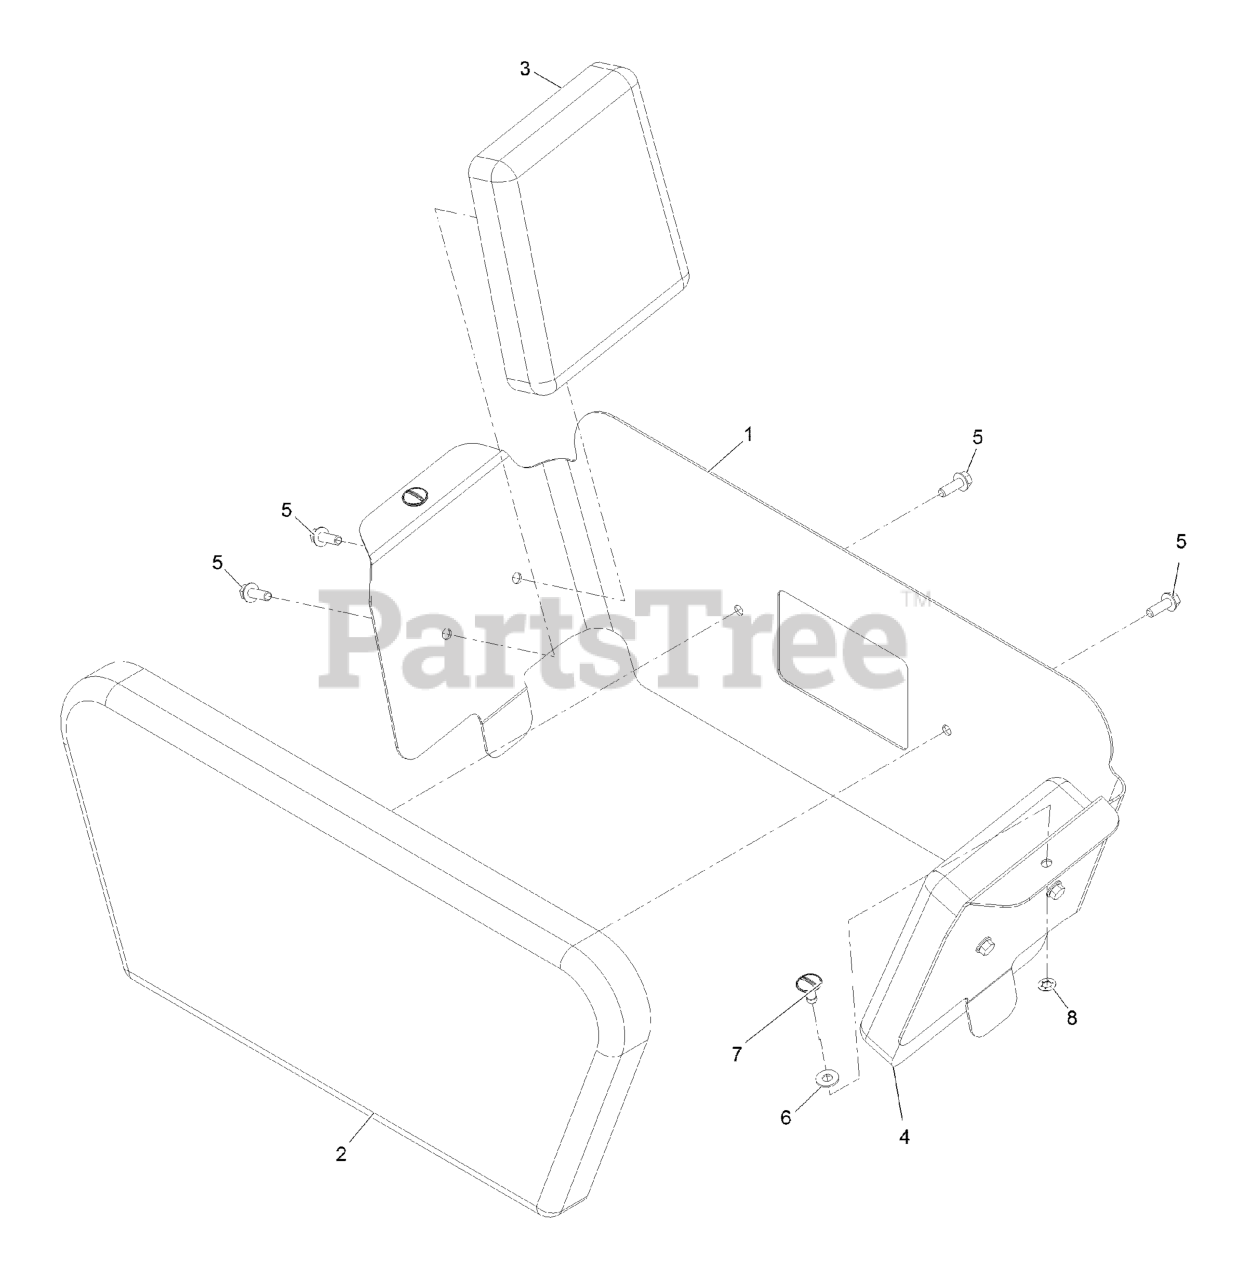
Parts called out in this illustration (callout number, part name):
1	BRACKET-PAD, KNEE
2	Pad-Knee, Center
3	PAD-KNEE, LH SIDE
4	PAD-KNEE, RH SIDE
5	SCREW-HHF
6	WASHER-FLAT
7	STUD-1/4 TURN
8	RETAINER-STUD
